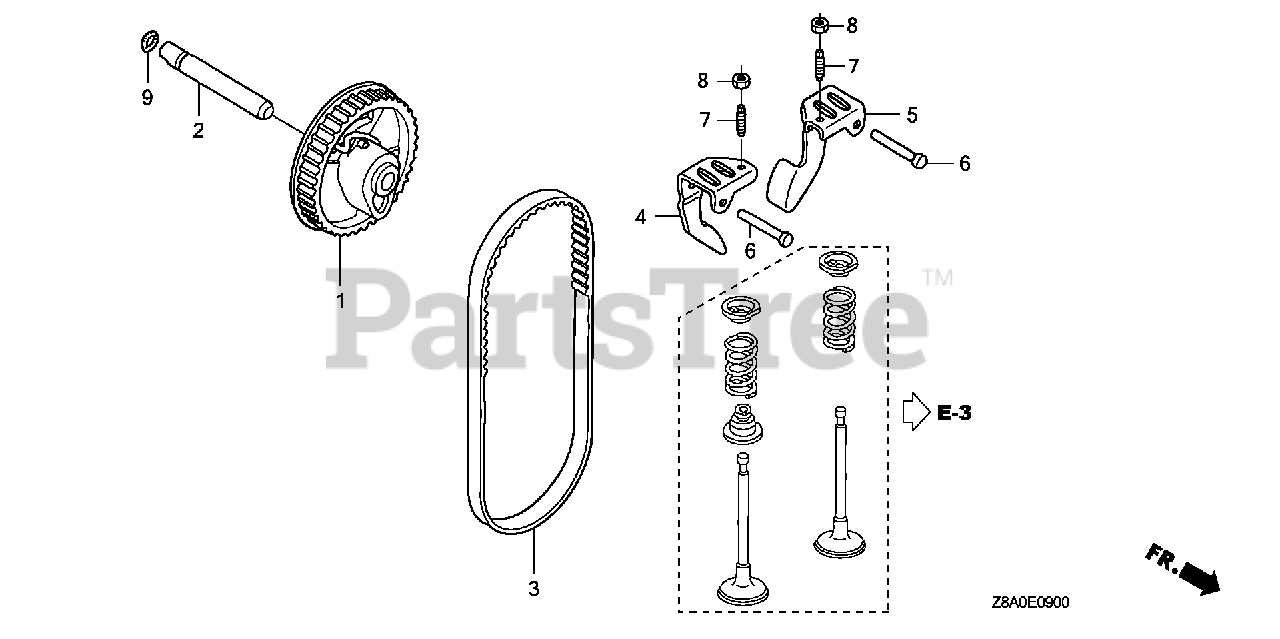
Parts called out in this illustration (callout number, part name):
1	PULLEY, CAMSHAFT
2	SHAFT, CAM PULLEY
3	BELT, TIMING (84HU6 G-200)
4	ARM, IN. VALVE ROCKER
5	ARM, EX. VALVE ROCKER
6	SHAFT, ROCKER ARM
7	SCREW, TAPPET ADJ.
8	NUT, TAPPET ADJ.
9	O-RING (6.8X1.9) (ARAI)
